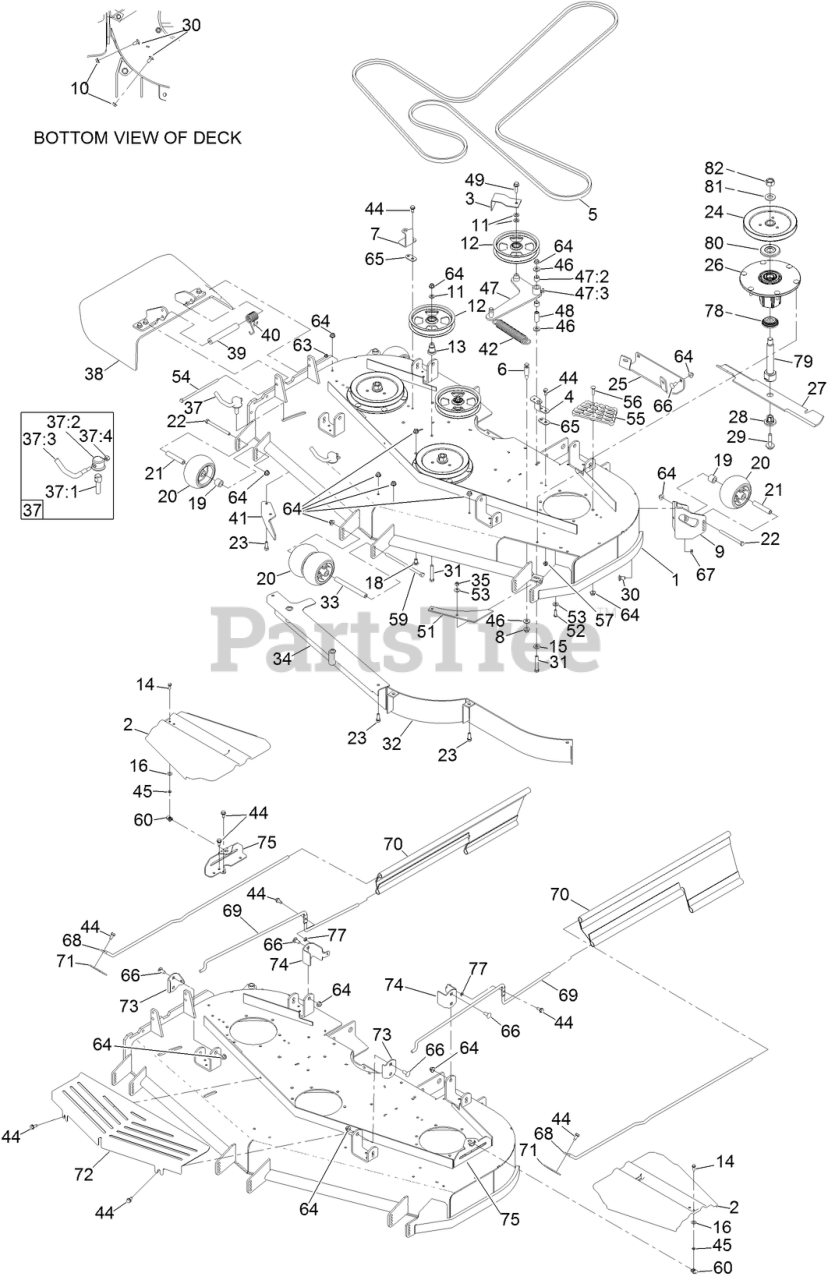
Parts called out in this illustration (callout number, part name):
1	DECK DECAL ASM
2	COVER-BELT
3	GUIDE-BELT
4	BRACKET-COVER, TALL
5	BELT-V
6	PIN-THREADED, SPRING ANCHOR
7	BRACKET-COVER
8	NUT-HF
9	MOUNT-WHEEL, LH
10	NUT-HHF, WHIZ
11	WASHER-FLAT
12	PULLEY-IDLER, FLAT
13	MOUNT-PULLEY
14	SCREW-HWH
15	WASHER-BELLEVILLE
16	WASHER-THRUST
18	SCREW-CARR
19	TUBE-SPACER
20	ROLLER-SCALP, ANTI
21	TUBE-SPANNER
22	SCREW-HH
24	PULLEY-B SECTION
25	PLATE-SKID
26	SPINDLE ASM
28	BUSHING-HEX
29	SCREW-SEMS
30	SCREW-CARR
31	SCREW-HH
33	SPACER-WHEEL
34	BAFFLE ASM
35	NUT-LOCK, NI
37	LEVER ASM
37:1	SCREW-LOCK
37:2	CAP-LOCK
37:4	NUT-LOCK, NI
38	RUBBER DEFLECTOR ASM
39	SPACER
40	SPRING-TORSION
41	BAFFLE-DISCHARGE
42	SPRING-EXTENSION
44	SCREW-HWHTF
45	PUSHNUT-RETAINER, BOLT
46	WASHER-FLAT
47	DECK IDLER ARM ASM
47:2	SLEEVE-BEARING
47:3	FITTING-GREASE, 90 DEG
48	BUSHING
49	SCREW-HHF
51	PLATE-TURBO
52	SCREW-HSBH
53	WASHER-SPRING
54	SCREW-HH
55	STEP-DECK
56	SCREW-CARR
57	NUT-HF, NI
59	SCREW-HH
63	NUT-LOCK, NI
64	NUT-HF, NI
65	SPACER-BELT COVER
66	SCREW-CARR
68	ROD-SUPPORT, UPPER
69	ROD-SUPPORT, LOWER
70	GUARD-SIDE
71	BRACKET-MOUNTING, UPPER ROD
72	SHIELD-FRONT, DECK
73	BRACKET-MOUNTING, FRONT
74	BRACKET-MOUNTING, REAR
75	BRACKET-SUPPORT, SPINDLE COVER
77	NUT-PUSH
78	GUARD-BOTTOM
79	SHAFT-SPINDLE
80	GUARD-BEARING, TOP
81	WASHER
82	NUT-HEX
